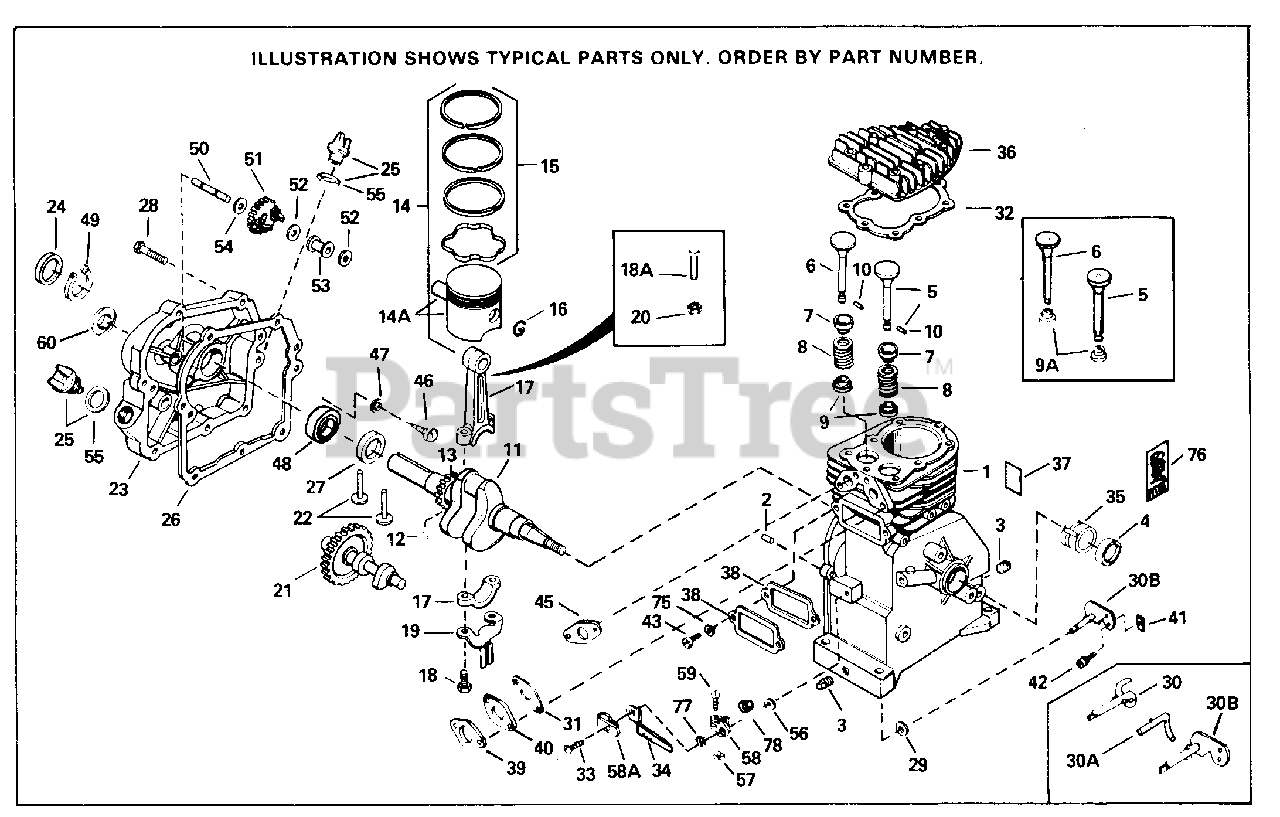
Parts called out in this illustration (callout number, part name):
1	"Cylinder (CI liner)(Incl. 2, 3, 4, 35 ) 2-5/16"
1	Cylinder (Incl. 2, 3 & 4) 2-1/2" Bor e
2	Dowel Pin
3	Oil Drain Plug (Sq. hd., 1/4-18)
4	Seal, Oil
5	Intake Valve (Std.) (Incl. 151)
5	Exhaust Valve (1/32" OS) (Incl. 151)
5	Intake Valve (Std.) (Incl. 9A)
6	Exhaust Valve (1/32" OS) (Incl. 151)
6	Exhaust Valve (Std.) (Incl. 9A)
6	Exhaust Valve (1/32" OS) (Incl. 9A)
6	Exhaust Valve (Std.) (Incl. 151)
7	Cap, Upper valve spring
8	Spring, Valve
9A	Cap, Lower valve spring
11	Crankshaft (Incl. 24)
12	Pin, Crankshaft gear only)
13	Crankshaft Gear Early production onl y
14	Piston Ass'y (Std.)(Incl. 14A,15,16) 2-5/16"
14	Piston, Pin & Ring Set (Std.) 2-1/2" Bore
14	Piston, Pin & Ring Set (.010" OS)
14	Piston, Pin & Ring Set (.020" OS)
14	Piston Ass'y (.010 OS) Incl. 14A, 15 & 16
14	Piston Ass'y (.020 OS) Incl. 14A, 15 & 16
14A	Piston & Pin Ass'y. (Std.)(Incl. 16) 2-5/16"
14A	Piston & Pin Ass'y. (Std.)(Incl. 16) 2-1/2"
14A	Piston & Pin Ass'y. (.010" OS) Incl. 16
14A	Piston & Pin Ass'y. (.020" OS) Incl. 16
15	Ring Set (Std.)
15	Ring Set (.010" OS)
15	Ring Set (.020" OS)
15	Ring Set (Std.) (2-5/16" Bore)
16	Piston Pin Retaining Ring
17	Connecting Rod (Incl. 18 & 19)
18	Bolt, Connecting rod Late Production
18A	Bolt, Connecting rod Early Productio n
19	Oil Dipper
20	Nut, Lock (Used on Early Production)
21	Camshaft
22	Valve Lifter
23	Cover, Cylinder (Incl. 24, 25 & 50)
24	Oil Seal
24	Oil Seal equired)
24	Oil Seal (1-1/4", 1/4" thick) Use as required
25	Oil Fill Plug (Incl. 312) also availa ble in Packaged Part #740079
26	Cylinder Cover Gasket
28	Screw, 1/4-20 x 1" (Use as required)
28	Screw, 1/4-20 x 1-1/4" Use as requir ed
29	Flat Washer
30	Rod, Governor (Incl. 29) NOTE: To de termine which governor rod to use for Models SBH-7C,SBH-24C, SBH-47,C,D, a nd SBH-48,C,D, visibly compare rod fr om original engine. If rod from orig inal engine is not available for visi ble comparison, refer t
30A	Rod, Governor NOTE: To determine whi ch governor rod to use for Models SBH -7C,SBH-24C, SBH-47,C,D, and SBH-48,C ,D, visibly compare rod from original engine. If rod from original engine is not available for visible compari son, refer to parts list
31	Intake Pipe Gasket quired)
31	Flange Gasket (1/16" thick) Use as re quired
31	Intake Gasket (1/8" thick) Use as req uired
32	Cylinder Head Gasket
34	Lever, Governor
35	Bushing, Crankshaft (Use as required)
36	Cylinder Head Not included with bloc k
37	Decal, Instruction
38	Valve Cover Gasket
38	Gasket, Breather (Use as required)
43	Screw, 10-24 x 1/2"
45	Intake Pipe Gasket
45	Exhaust Gasket
46	Screw, 10-24 x 9/16"
48	Ball Bearing
49	Bearing Retainer
50	Shaft, Mechanical governor
51	Gear Assy., Governor (Incl. 54)
52	Retaining Ring
53	Spool, Governor
54	Washer, Flat
55	Oil Fill Plug Gasket
58A	Clamp, Governor lever
76	Decal, Name
